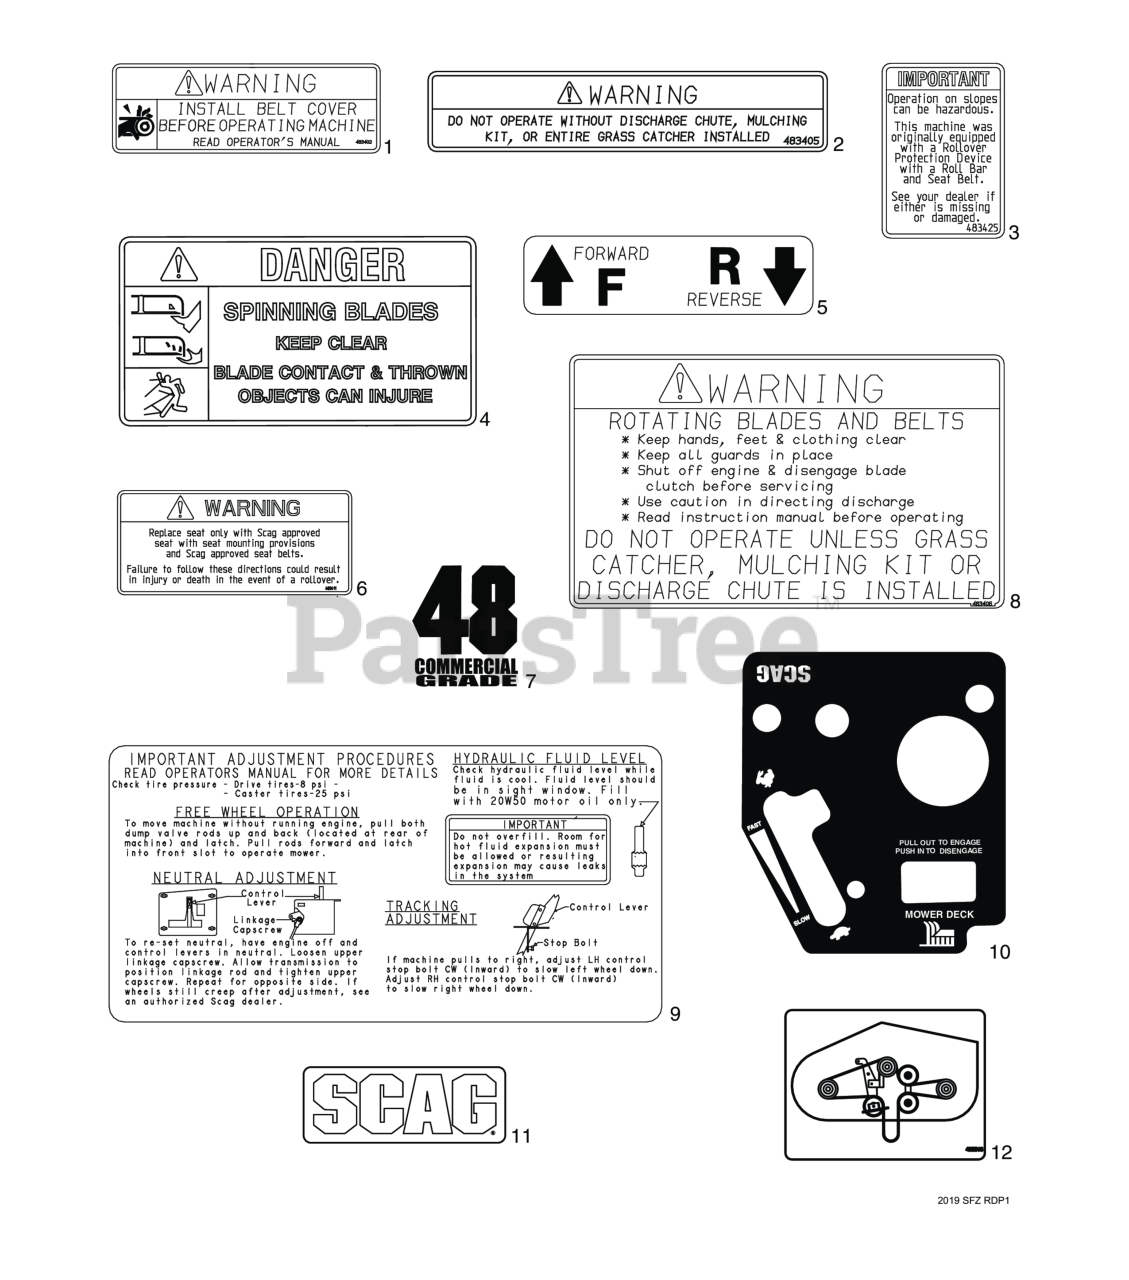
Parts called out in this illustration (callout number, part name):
1	Decal, Warning - Belt Cover
2	Decal, Warning-Discharge
3	Decal, ROPS
4	Decal, Spinning Blades
5	Decal, Traction Control
6	Decal, Seat Replacement
7	Decal, 48 Commercial
8	Decal, Warning - Rotating Blades
9	Decal, Adjustment SFZ
10	Decal, Instrument Panel - SFZ48, SFZ52 & SFZ 61
11	Decal, Scag - Fuel Tank
12	Decal, SZL / SFZ / SPZ Belt Routing
